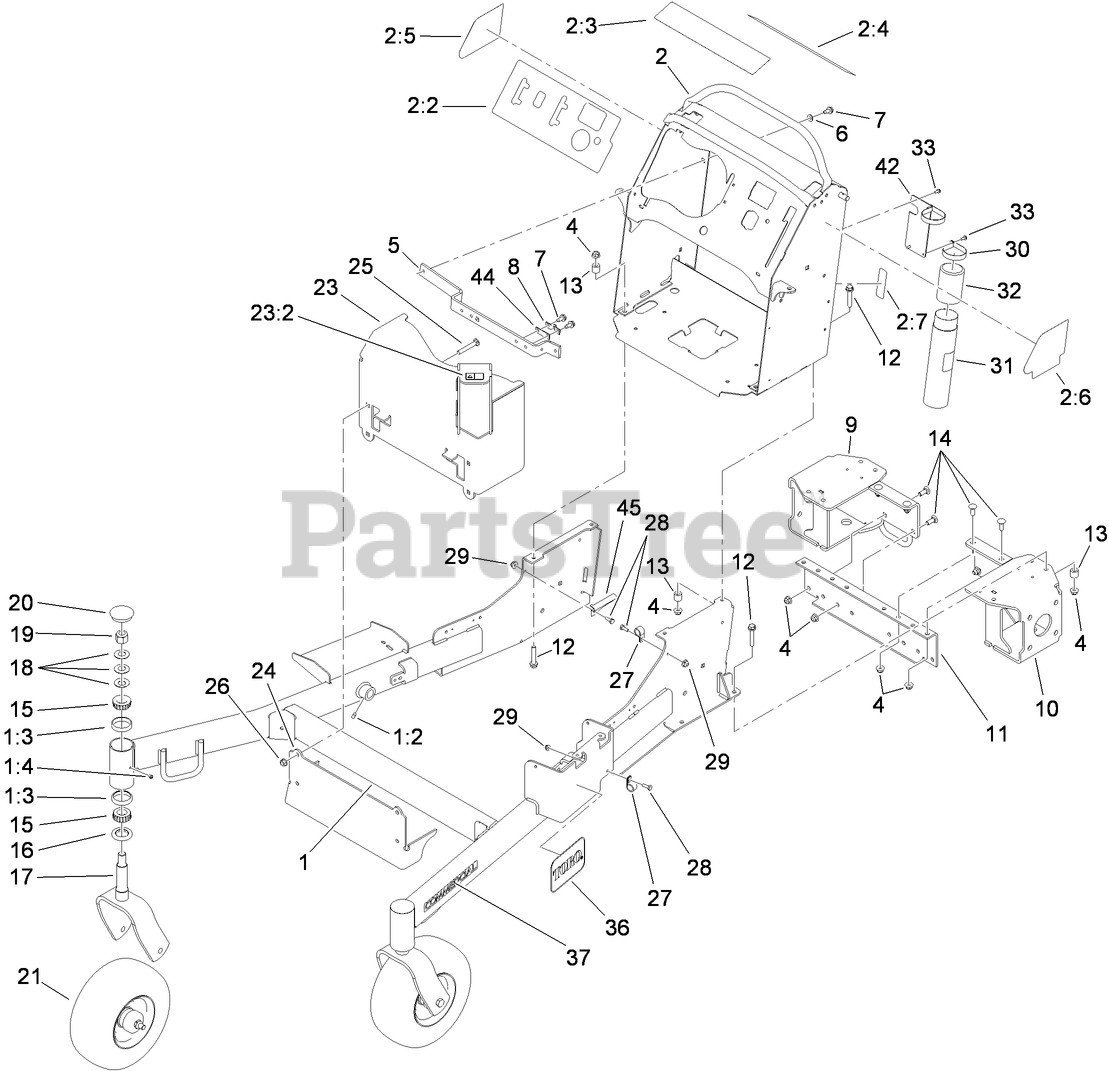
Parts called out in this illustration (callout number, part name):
1	FRONT FRAME ASM
1:2	FITTING-GREASE
1:3	CUP-BEARING
2	CONTROL TOWER ASM
2:2	DECAL-PANEL, CONTROL
2:3	DECAL-OPC
2:4	DECAL-WARNING
2:5	DECAL-HOC
2:6	DECAL-AID, SERVICE
2:7	DECAL-FUSE
4	NUT-HF, NI
5	BAR-CABLE
6	WASHER-PLAIN
7	SCREW-HWHTF
8	CLAMP-CABLE
9	MOUNT-MOTOR, RH
10	MOUNT-MOTOR, LH
11	MOUNT-MOTOR, CENTER
12	SCREW-HHF
13	SPACER
14	SCREW-CARR
15	BEARING-ROLLER, TAPERED
16	SEAL-GREASE
17	FORK-CASTER
18	WASHER-BELLVILLE
19	NUT-LOCK, NI
20	CAP-GREASE
21	WHEEL/TIRE AND BEARING ASM
23	MUFFLER GUARD ASM
23:2	DECAL-WARNING
24	PANEL-GUARD
25	SCREW-CARR
26	NUT-HF
27	CLAMP-CABLE
28	SCREW-HH
29	NUT-HF
30	CLAMP-R
31	TUBE-MANUAL
32	CAP-HOUSING
33	SCREW-TAPTITE
36	DECAL
37	DECAL-COMMERCIAL
42	PLATE-MANUAL
44	SHIM-CABLE
45	BRACKET-HOSE, FUEL
